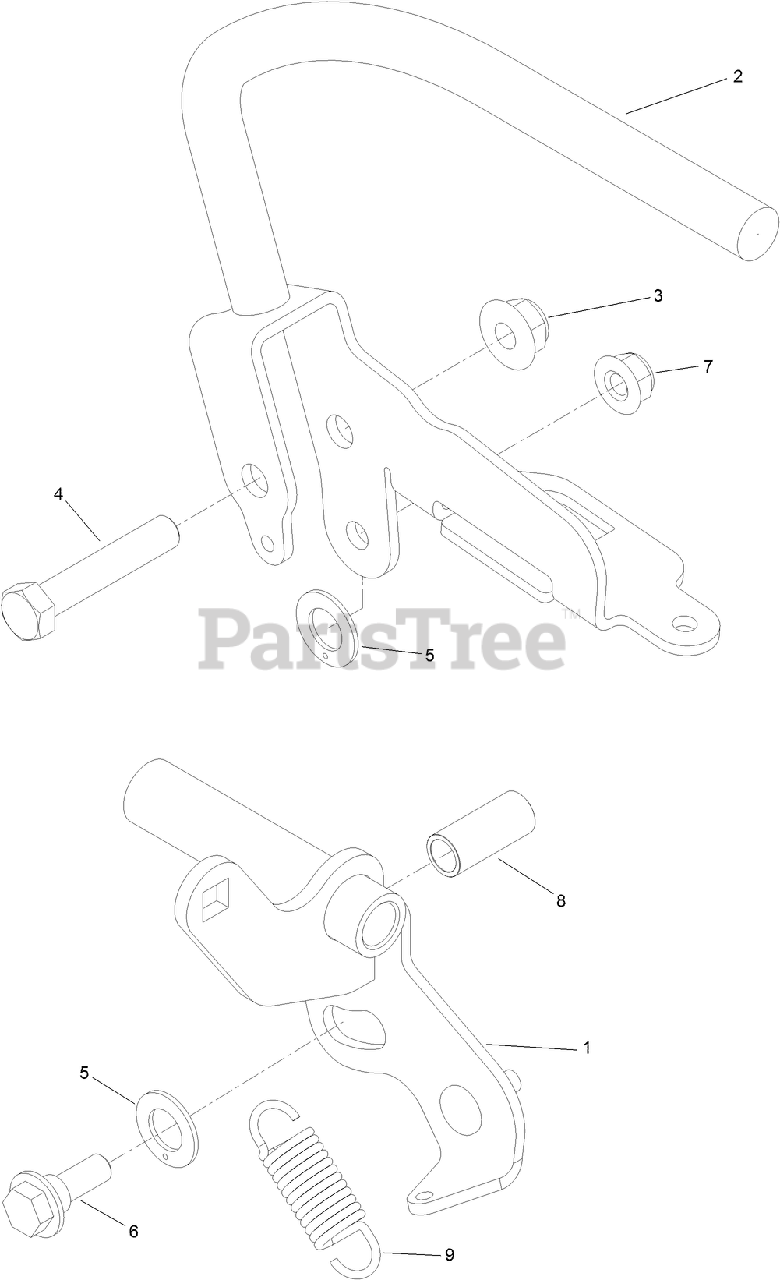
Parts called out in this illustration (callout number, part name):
2	LEVER-RH
3	NUT-HF, NI
4	SCREW-HH
5	WASHER-THRUST
6	SCREW-SHOULDER
7	NUT-HF, NI
8	BEARING-SLEEVE
9	SPRING-EXTENSION
